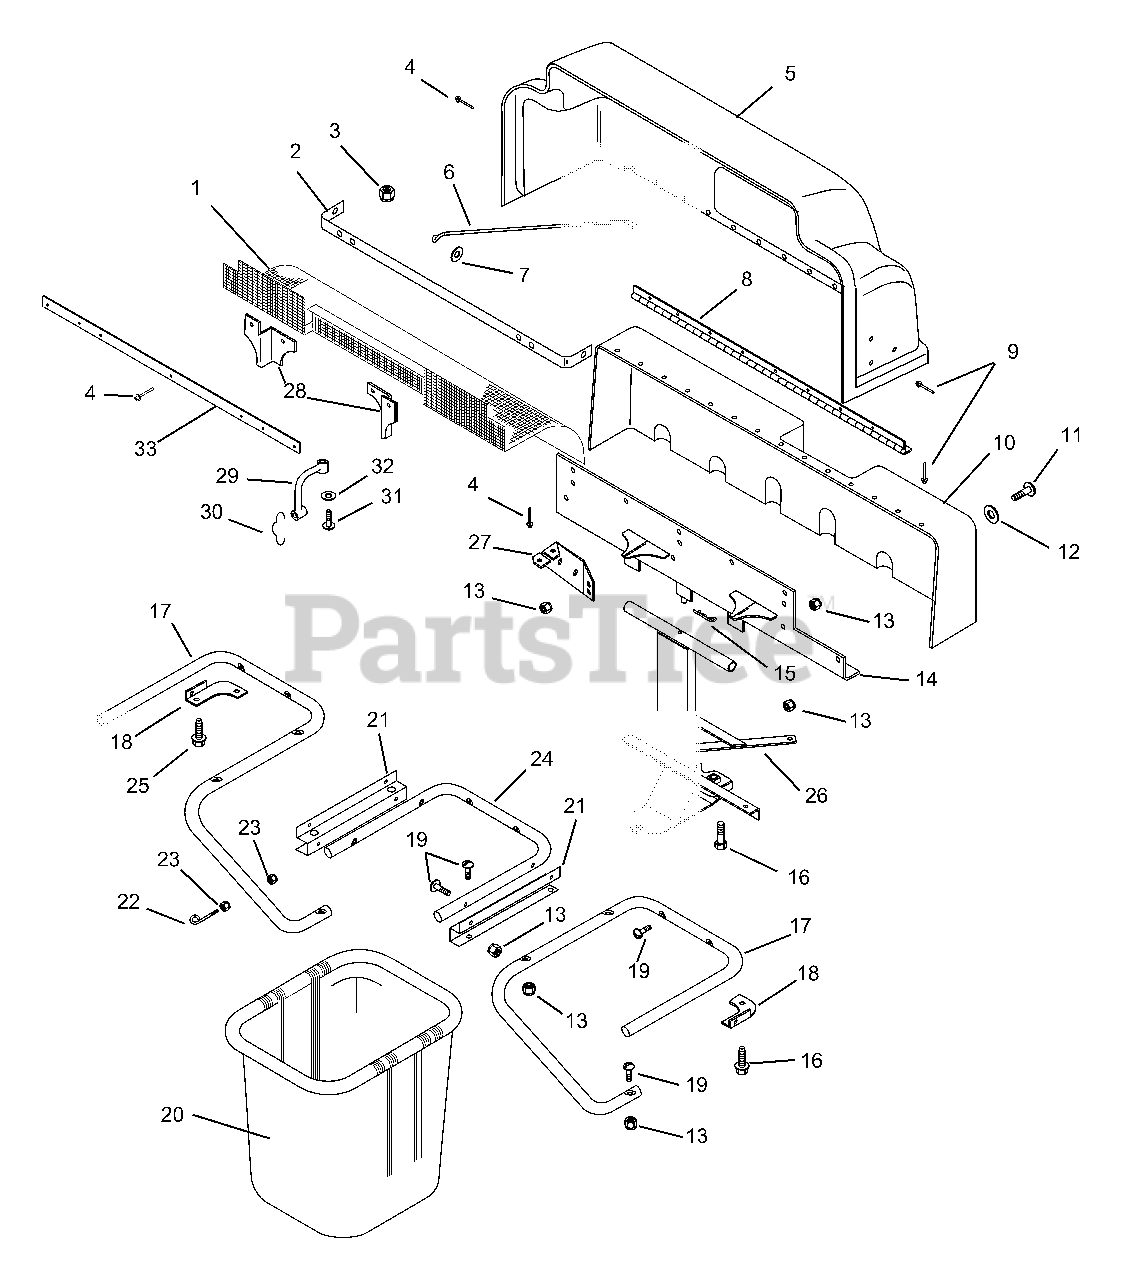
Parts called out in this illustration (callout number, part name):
1	Screen
2	Screen Mounting Bracket
3	Nut-Locking-Top 10-24
4	Rivet-Pop .187 x .527
5	Hinged Cover w/Decals
6	Brace
7	Washer-Flat-Steel .194 x .492 x .047
9	Rivet-Pop .187 x .402
10	Stationary Cover
11	Bolt-Hex .31-18 x 1.00 Grade 2
12	Washer-Flat-Steel .344 x .063
13	Nut- Locking-Nylon .312-18 Grade 2
14	Mounting Bracket
15	Pin-Hair Internal .08 x .38 x 1.42
16	Bolt-Hex .50-13 x 1.25 Grade 2
17	Right Tube
17	Left Tube
18	Right Hand Corner Bracket
18	Left Hand Corner Bracket
19	Screw-Machine .31-18 x 1.50
20	Grass Bager Basket
21	Tube Bracket
22	Eyebolt
23	Nut-Locking-Center .250-20
24	Center Tube
25	Screw-Tapping .312-18 x .50
26	Bagger Frame
27	Brace
28	Baffle Left Hand
28	Baffle Right Hand
29	Battery Strap
30	Hook
31	Screw-Machine 10-24 x 1.00
32	Washer-Flat Steel .219 x .50 x .049
33	Guard, Screen
